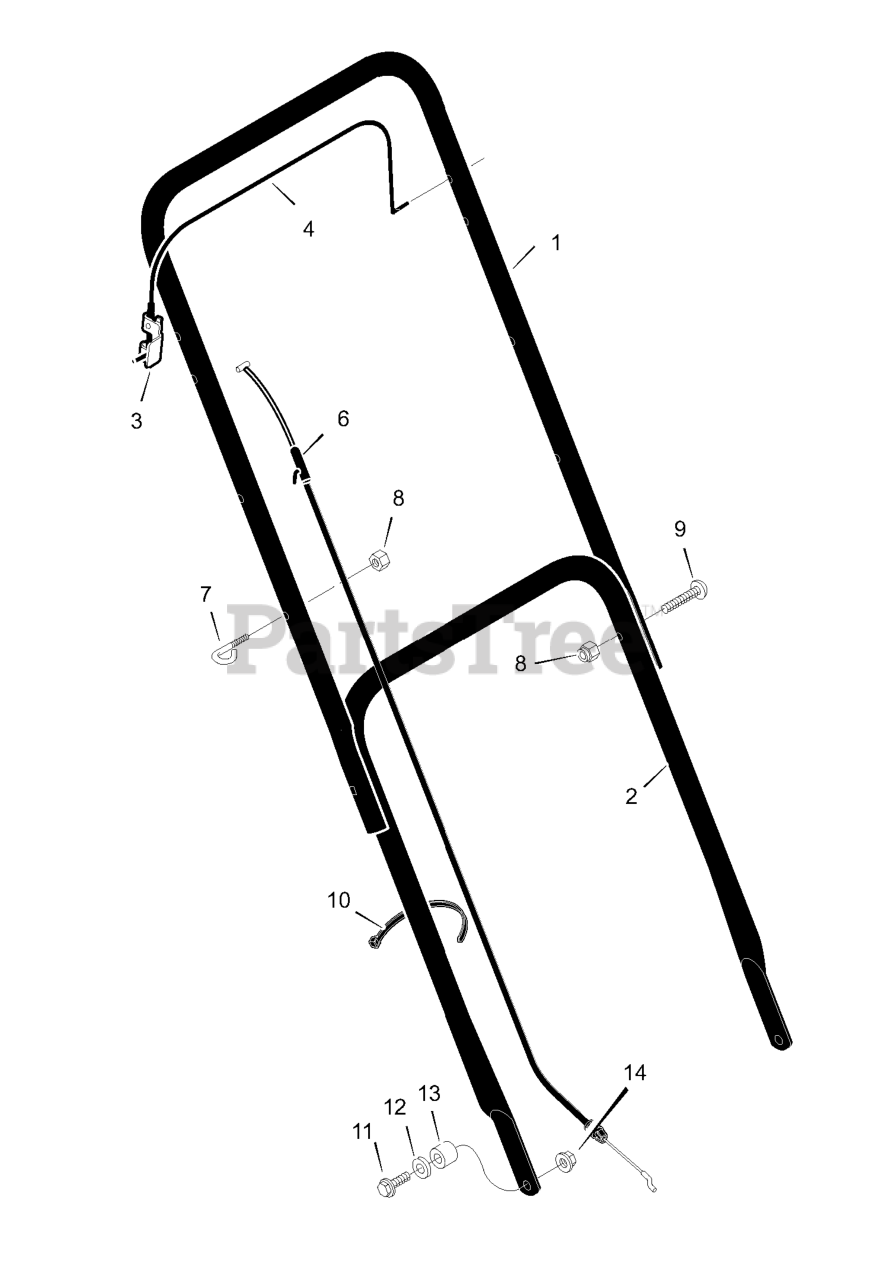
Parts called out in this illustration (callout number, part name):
1	Handle, Upper (Black)
2	Handle, Lower (Black)
3	Bracket, Stop Lever
4	Lever, Stop
6	Engine Stop Cable
7	GUIDE, ROPE
8	Locknut
10	Fastener, Cable
11	Bolt
14	Nut
